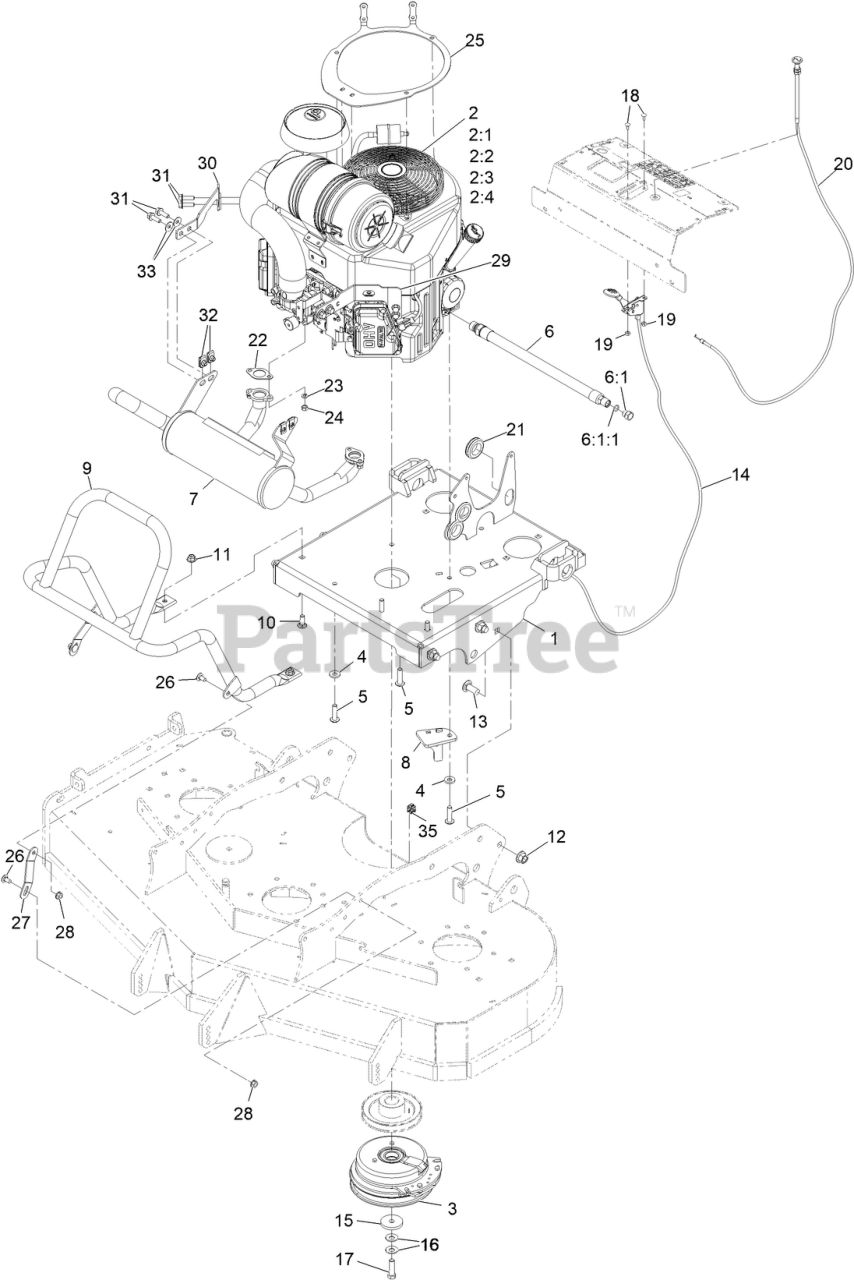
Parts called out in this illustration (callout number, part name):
1	WLD-ENGINE DECK
2:1	Kawasaki 49065-7007 Engine Oil Filter
2:2	Kawasaki 49019-7005 Fuel Filter
2:3	Kawasaki 11013-7045 Safety Filter
2:4	Kawasaki 11013-7044 Engine Air Filter
4	WASHER-BELLEVILLE
5	SCREW-BHTF
6	ASM, ENGINE OIL DRAIN HOS
6:1	PLUG-HH
6:1:1	O-RING
7	MUFFLER-KAWASAKI
8	ASM-CLUTCH ANCHOR
9	Tube-Guard Muffler
10	SCREW-CARR
11	NUT-HF, NI
12	Nut-Lock 1/2-13
13	SCREW-CARR, SHORT NECK
14	CONTROL,THROTTLE
15	WASHER-CLUTCH
16	WASHER-SPRING
17	SCREW-HH 7/16-20 X 1 1/2 W/LOCTITE
18	BOLT-CARR
19	NUT-LOCK, NI
20	CABLE-CHOKE
21	GROMMET
22	GASKET-EXHAUST
23	WASHER-LOCK
25	BRACKET- ENGINE FILTER
26	SCREW-CARR
27	Strap, Muffler Guard
29	BRACKET-MUFFLER, FRONT
30	BRACKET-MUFFLER, REAR
31	SCREW-HHF
33	WASHER-BELLEVILLE
35	Clip-Edge W/Tie, Perpendicular
